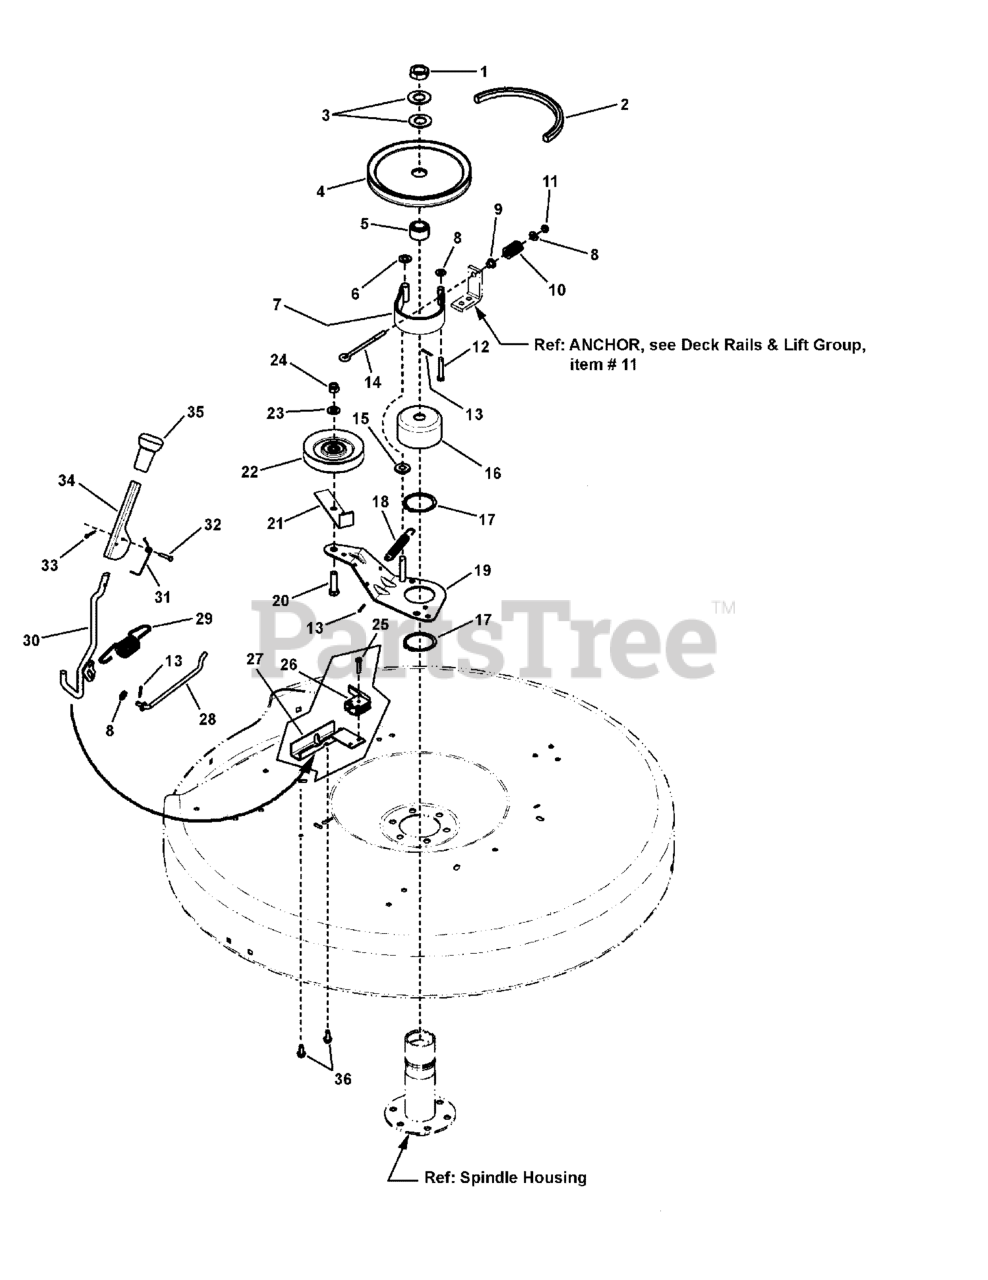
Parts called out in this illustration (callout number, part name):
1	NUT, 3/4-16 Hex Jam, GR 8
2	* BELT, Drive (72.75" AA Section)
3	WASHER, 49/64" I.D. x 1-1/2" O.D. Flat
4	PULLEY, Deck
5	HUB, Pulley (Powdered Metal)
6	WASHER, 3/8" Flat SAE
7	KIT, Brake Band (Formed)
8	WASHER, .28 x .63 x .06 Flat, GR 5
9	BUSHING, Flange .27 x .35 x .4
10	SPRING, Rectangular Wire Die, Blue
11	NUT, 1/4-20 Hex Top Lock
12	PIN, 1/4 x 1-5/8" Clevis
13	PIN, 3/32 x 3/4" Cotter
14	EYE-BOLT, 1/4-20 x 4"
15	SPACER, .39 x 1.0 x .31 Nylon
16	DRUM, Brake Spindle, 3" OD, 1.6" Tall
17	RING, 2" External Retaining
18	SPRING, Extension, 4" x 1/2" Diameter
19	WELDMENT, Idler Arm
20	SCREW, 3/8-16 x 1-1/2" Hex Head Cap, GR 5
21	RESTRICTOR, Belt
22	PULLEY, Idler, 3/8" ID, 4" OD
23	WASHER, 3/8" Flat
24	NUT, 3/8-16 Hex Nyloc
25	SCREW, #10-32 x 1" Hex Washer Head Self-Tap
26	SWITCH, Deck Interlock (NO)
27	MOUNT, Handle/Switch
28	ROD, Idler Control
29	SPRING, Blade Handle
30	WELDMENT, Blade Engagement Handle
31	SPRING, Torsion, Flip Handle
32	PIN, 3/16 x 1" Clevis
33	PIN, 3/32 x 1/2" Cotter
34	HANDLE, Blade Engagement (Flip)
35	GRIP, Handle
36	SCREW, 1/4-20 x 5/8" Hex Washer Head Self-Tap
